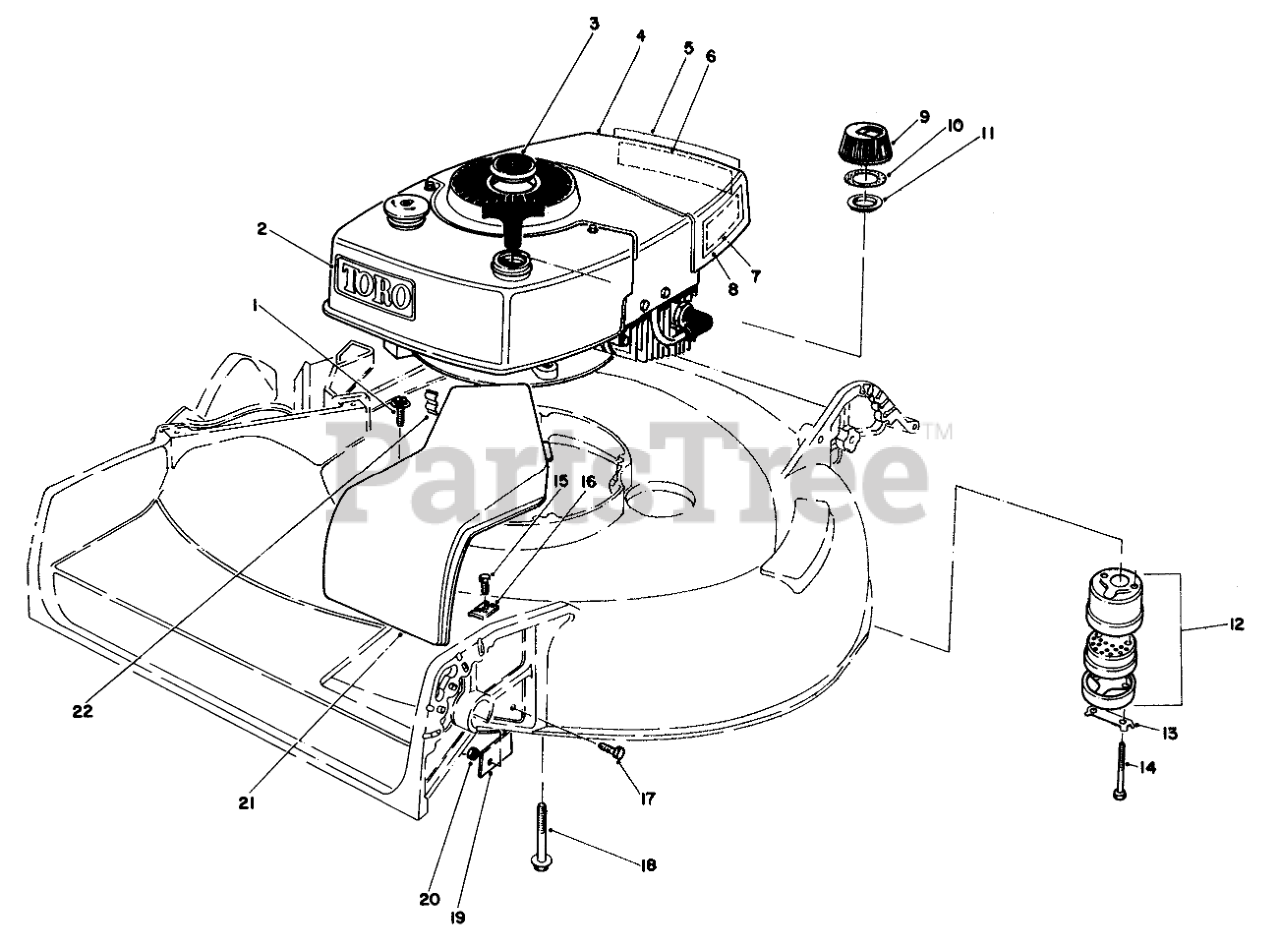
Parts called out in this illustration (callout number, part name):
1	SCREW
2	Decal Tow
3	Plug Button
4	Engine
5	Decal-Danger
6	Decal Maintenance
7	Decal-Maintenance
8	Decal-Maintenance
9	Gas Cap Assembly (Incl. Ref. #10 & 11)
10	GASKET
11	GAS CAP BAFFLE
12	Muffler (Incl . Ref . #13 & 14)
13	CLIP - LOCKING
14	SCREW-HH
15	SCREW-HWHTF
16	Cable Clamp
17	SCREW-HH
18	3/8-16 X 2-3/4 CAPSCR
19	Shield Front
20	NUT-LOCK, NI
21	Cow-Belt
22	Clip Conduit
